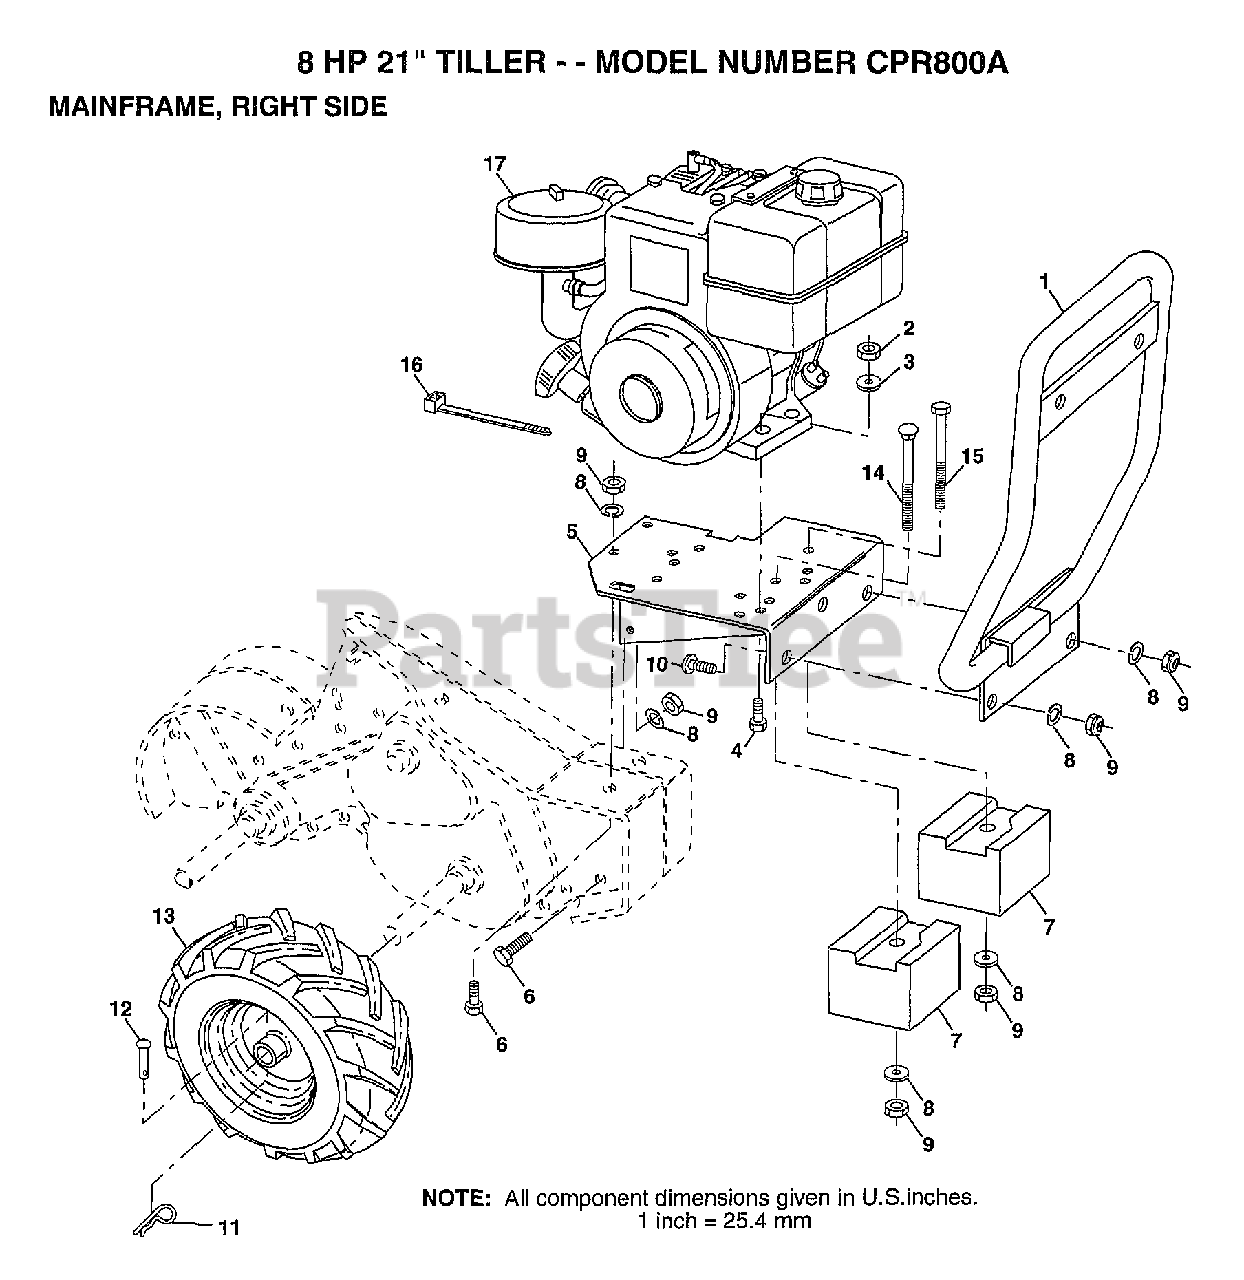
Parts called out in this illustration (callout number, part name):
1	BUMPER.ASM
2	NUT.HEX.5/16-18
3	LOCKWASHER
4	BOLT
5	"ASM. ENGINE, BASE"
6	BOLT
7	COUNTERWEIGHT CRT
8	LOCKWASHER
9	NUT.HEX.3/8-16UNC
11	SPRING.RETAINER
12	RIVET.PAN HD.1.75
13	TIRE TI
13	RIM.16X4X8.WHT
14	BOLT CRT
15	BOLT.3/8-16X4.5
16	TIE CABLE CRT
